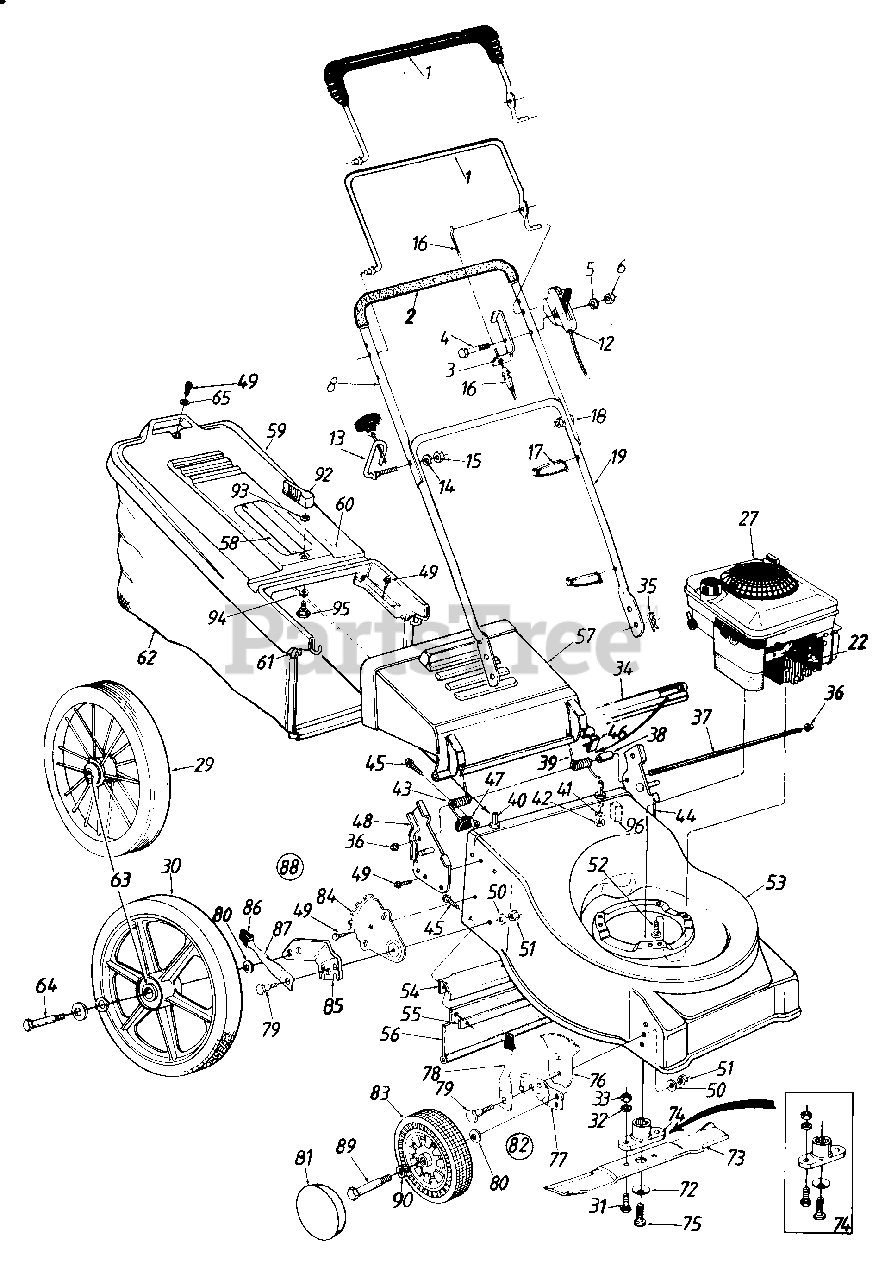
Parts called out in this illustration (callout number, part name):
1	Control Handle Ass'y.
2	Foam Grip
3	Cable Brkt.
4	Hex Bolt 1/4-20 x 2.0" Lg.
5	Spr. Wash. 1/4" I.D.
6	Hex Nut 1/4-20 Thd.
13	Rope Guide Bolt
14	L-Wash. 5/16" I.D.
15	Hex Nut 5/16-18 Thd.
16	Control Cable-40.5"
17	Cable Tie
18	Curved Carriage Bolt 5/16-18 x 1.38" Lg.
19	Lower Handle
22	Spark Plug Boot
27	Engine
29	Wheel Ass'y. Comp.-Steel Rim
30	Wheel Ass'y. Comp.-Plastic Rim
31	Hex Bolt 3/8-24 x 1"
32	L-Wash. 3/8" I.D.
33	Hex Nut 3/8-24 Thd.
34	Seal-Extrusion
35	Int. Cotter Pin 5/16" Dia.
36	Cap Speed Nut
37	Hinge Pin 17.75" Lg.
38	Spacer.255" I.D.
39	Torsion Spring-L.H.
40	Shld. Pin 3/8-24 x 1.43" Lg.
41	L-Wash. 3/8" I.D.
42	Hex Jam Nut 3/8-24 Thd.
43	Torsion Spring-R.H.
44	Handle Brkt. Ass'y.-L.H.
45	Torx Mach. AB-Tap Scr. 1/4 x .62" Lg.
46	Deflector Plug
47	Corner Plug
48	Handle Brht. Ass'y.-R.H.
49	Hex L-Wash. AB-Tap Scr. 1/4 x .62'1 Lg.
50	Bell-Wash..39" I.D.
51	Hex Nut 3/8-16 Thd.
52	Hex L-Wash. Hd. Scr. 3/8-16 x 1" Lg.
57	Rear Chute Deflector
58	Hardtop Handle
59	Hardtop Bag Cover
60	Rear Catcher Frame
61	Front Catcher Frame
62	Grass Bag
63	Bearing 1/2" I.D.
64	Shld. Bolt .498" Dia. x 2.475"
65	Fl-Wash. .281" I.D.
72	Bell-Wash..46" I.D.
73	21" Blade
74	Blade Adapter Kit
75	Hex Bolt 7/16-20 x 1.5" Lg.
76	Height Adj. Plate
78	Spring Lever Ass'y. w/Knob
79	Shld. Bolt .50" Dia. x .357"
80	Bell-Wash. .38" I.D. x .88" O.D.
81	Hub Cap
82	Height Adj. Ass'y. Comp.-R.H.
83	Front Wheel Ass'y. Comp.
84	Index Plate
85	Pivot Bar-R.H.
86	Spring Lever Knob
87	Spring Lever
88	Rear Height Adj. Ass'y. Comp.-R.H.
89	Front Axle Bolt
90	Wave Wash. .53" I.D. x .78" O.D.
92	Grass Catcher Locking Knob
93	Internal L-Wash. 1/4" I.D.
94	Wave Washer 3/8" I.D.
95	Shld. Bolt .342" Dia. x .268"
